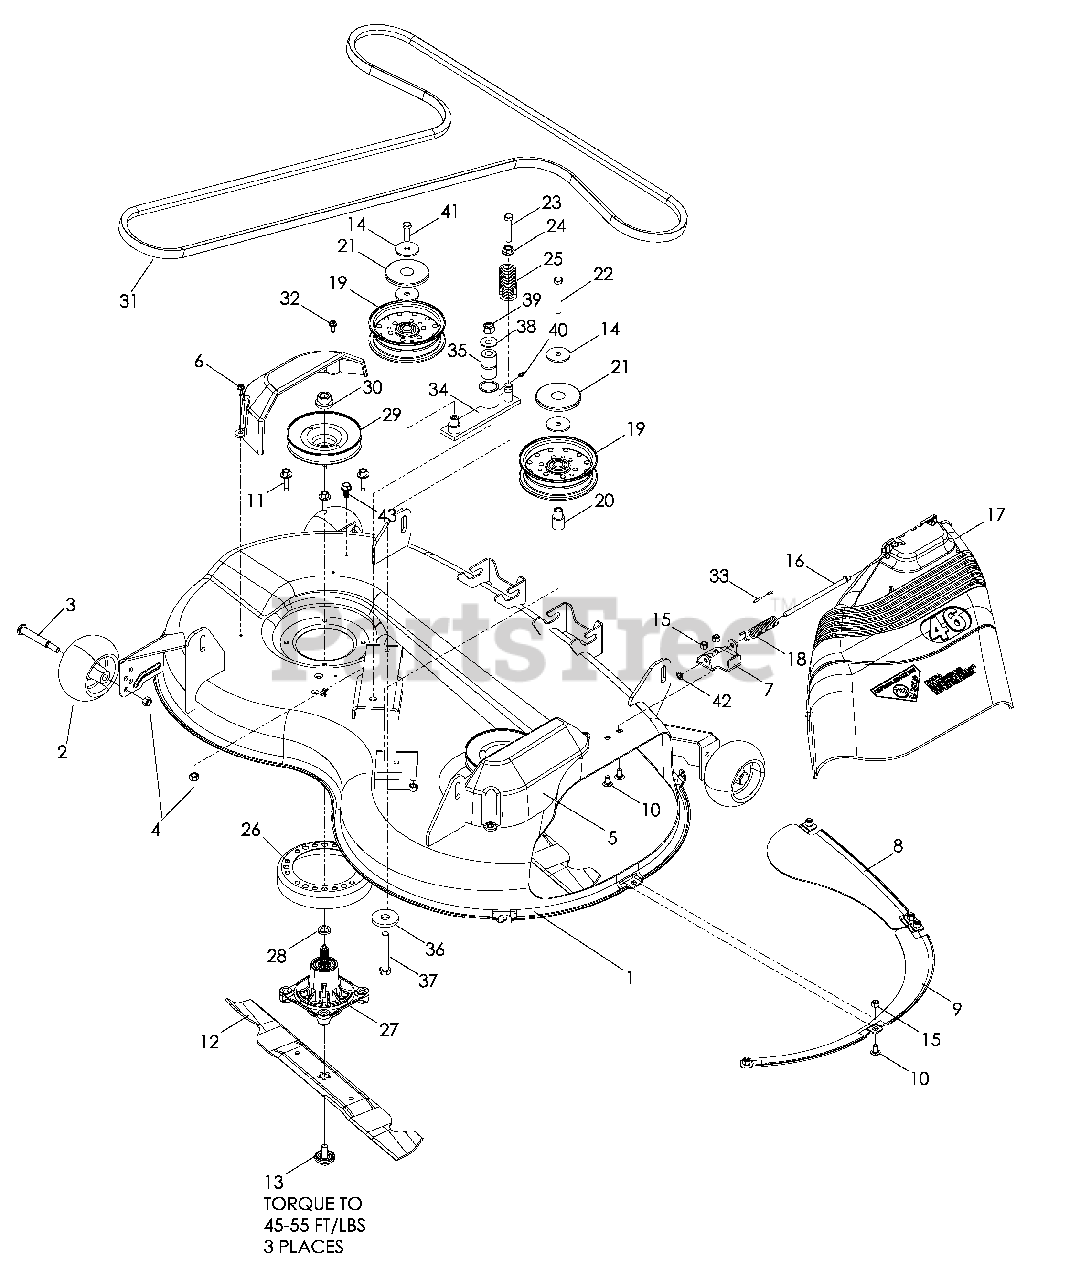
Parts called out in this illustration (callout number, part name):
1	DECK W/DECALS
2	WHEEL GAUGE
3	SB ½ x 25/8
4	NUT 3/8-16 NYLOC
5	SHIELD, BELT, RIGHT
6	SHIELD, BELT, LEFT
7	BRACKET, DEFLECTOR
8	BAFFLE, FRONT
9	BAFFLE, FRONT, RIGHT
10	RHSNB 5/16-18 x 5/8
11	SCREW 5/16-18 x 13/8 WSH HD
12	BLADE 46" HI-LIFT
13	BOLT, WASHER 7/16-20 UNF
14	WASHER 3/8 SPECIAL
15	NUT 5/16-18 NYLOC
16	ROD, HINGE
17	SHIELD, DEFLECTOR
18	SPRING, TORSION
19	PULLEY, IDLER
20	BUSHING, IDLER
21	TOP DUST CAP
22	HCS 3/8-16 x 2¾
23	HCS 3/8-16 x 2
24	NUT 3/8-16 WHIZLK
25	SPRING, EXTENSION
26	STRIPPER, ROUND
27	CUTTER HOUSING
28	WASHER, SPACER
29	PULLEY, DRIVEN
30	NUT 9/16 TOP CNTRLOCK
31	BELT, DECK
32	SCREW ¼-20 x 5/8 THDROLL
33	CAP, SLEEVE
34	ARM, IDLER
35	BUSHING, PIVOT
36	WASHER .65 SUPPORT
37	HCS ½-13 x 3¼
38	WASHER 9/16
39	NUT ½-13 NYLOC
40	ZERK
41	HCS 3/8-16 x 1¼
42	PUSHNUT
43	SCREW 3/8-16 x ¾ THD CUT
